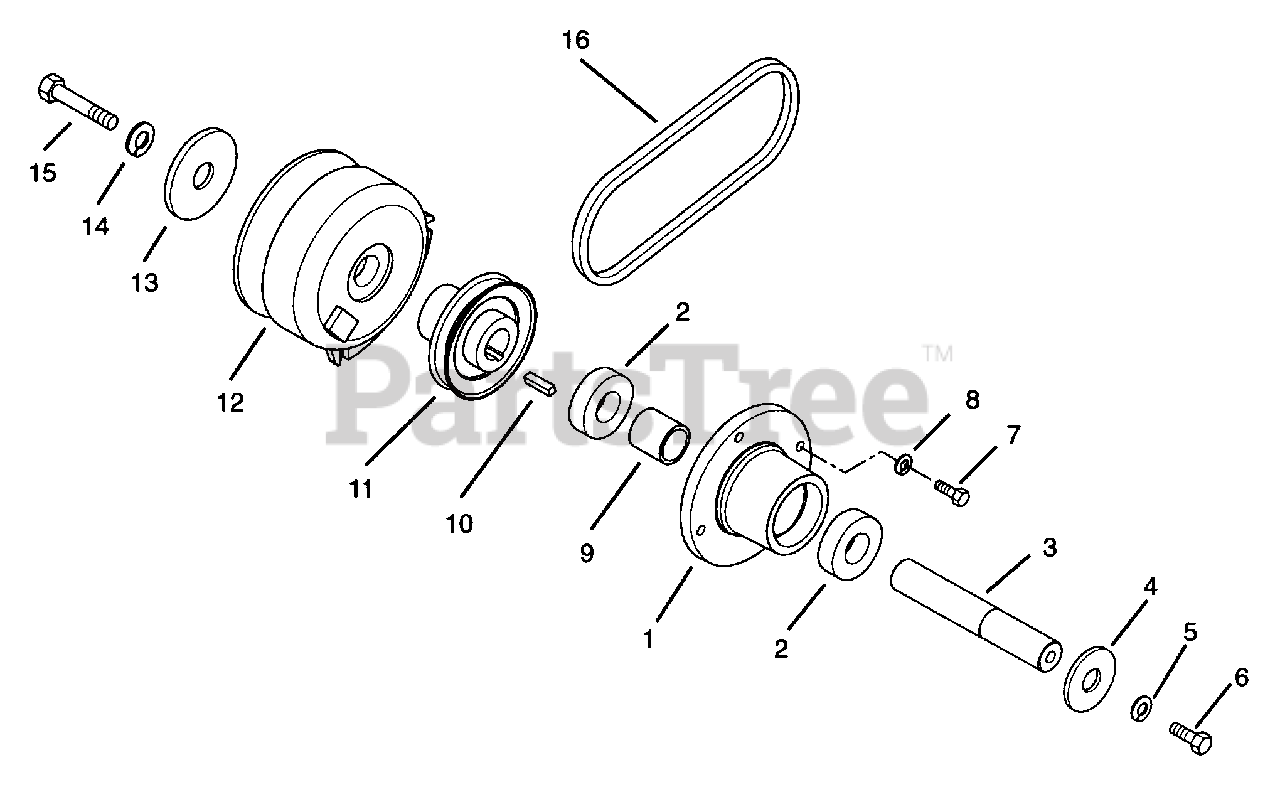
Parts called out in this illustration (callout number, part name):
1	HOUSING, TRANS SPNDL, BLACK
2	BRG-BALL .984X2.04X.59
3	SHAFT
3	SHAFT, JACK
3	SHAFT 1540/1648
4	WSHR-FL-STL .406 X 1.125 X .25
5	WSHR-LK .375X.094 MED PL
6	BLT,HEX 3/8-24 X 1.00
7	BLT-HEX .31-18X.75 PL GR5
8	WSHR-LK .313X.078 PL MED
9	SPACER 1.0X1.253X1.26
10	KEY-SQ .25X1.0X.25 SAE 8630
11	SHEAVE, JACKSHAFT
12	ELECTRIC CLUTCH/BRAKE(1.8AMP)
13	WSHR-SPECIAL .469X2.000X.250
14	WSHR-LK .438X.133 HVY
15	BLT-HEX .44-20X2.50
16	BELT
